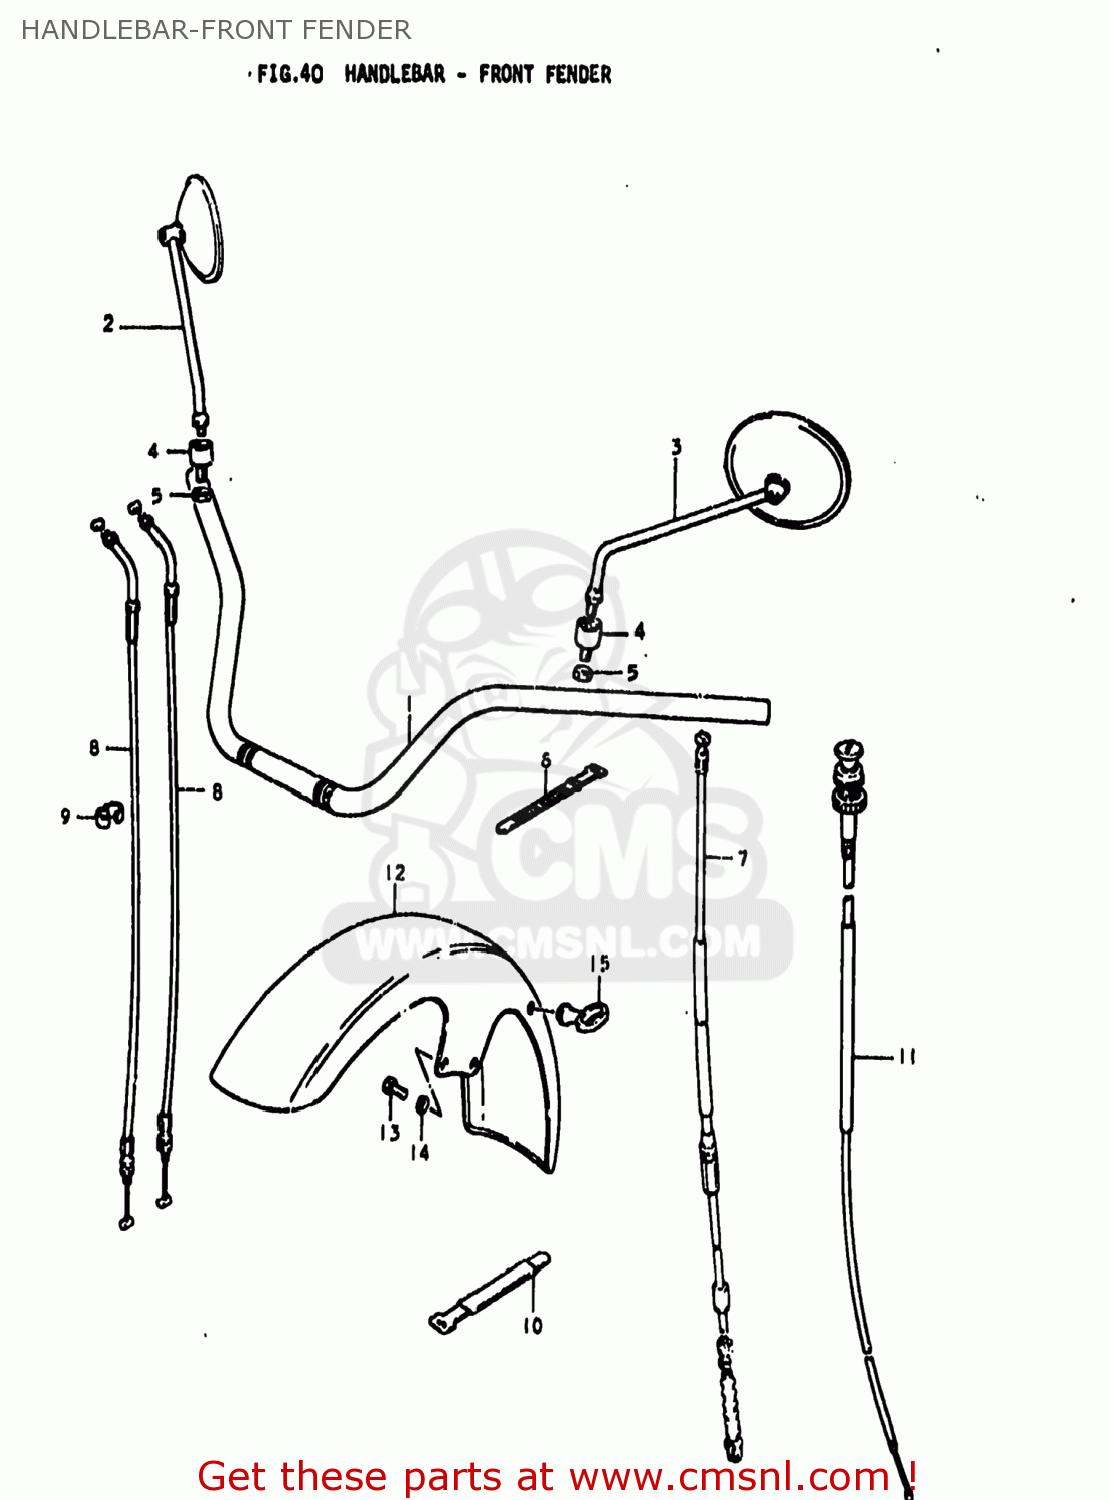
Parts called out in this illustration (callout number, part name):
1	HANDLEBAR
2	MIRROR ASSEMBLY,RIGHT
3	MIRROR ASSEMBLY,LEFT
4	CUSHION,REAR VIEW MIRROR
5	NUT
6	CLAMP(L:120)
7	CABLE ASSY,CLUTCH
8	CABLE ASSY,THROTTLE
9	CLIP
10	CLAMP
11	CABLE ASSY,STARTER
12	FENDER,FR
13	BOLT
14	LOCK WASHER
15	GUIDE,CABLE
